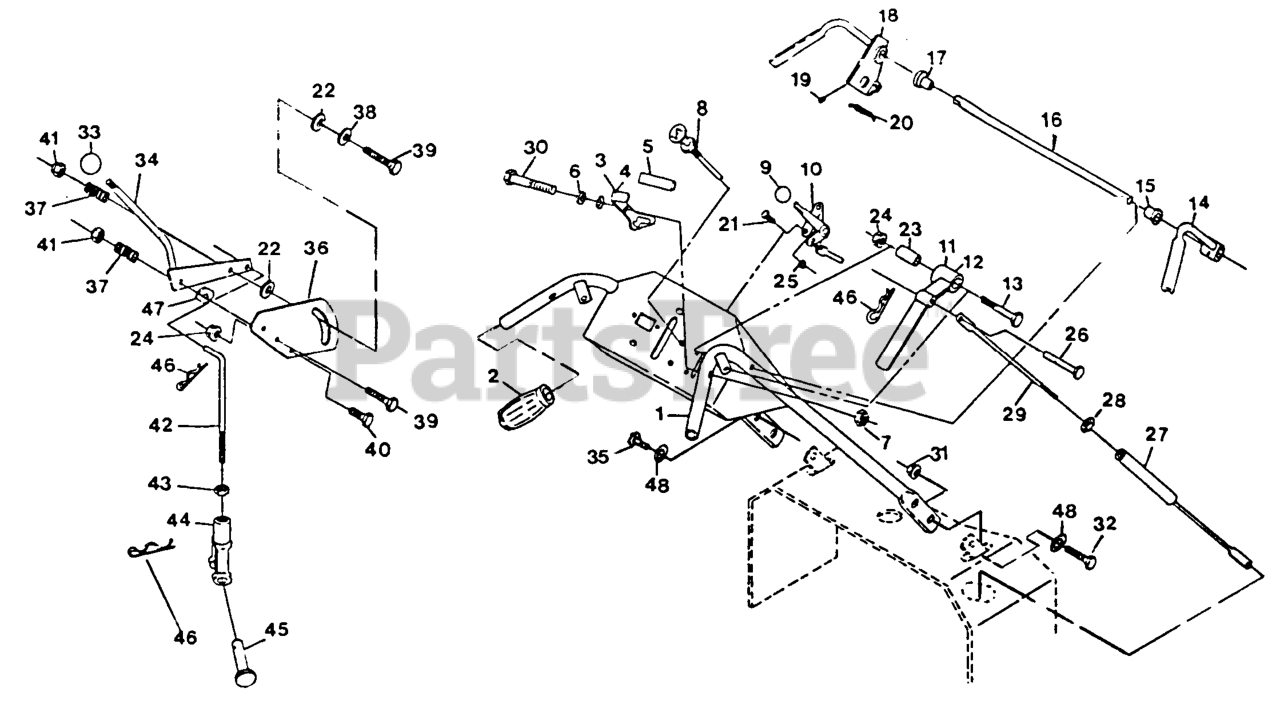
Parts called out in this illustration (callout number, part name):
3	LH LATCH W/GRIP
4	RH LATCH W/GRIP
5	GRIP-LATCH
6	WASHER-SPRING
8	CONTROL-CHOKE
9	KNOB-BALL
15	BUSHING-NYLON
16	ROD,CONNECTING
17	BUSHING,FLANGED
19	SCREW-SET
20	SPRING-EXTENSION
21	BOLT-CARR
22	WASHER-FRICTION
23	BUSHING-LEVER, DRIVE
26	PIN-CLEVIS
33	KNOB-BALL
36	PLATE-LEVER, SHIFTER
37	SPRING-COMPRESSION
38	WASHER-FRICTION
42	ROD,SPEED CONTROL
44	YOKE-ADJUSTABLE
45	PIN-CLEVIS
46	PIN-COTTER
